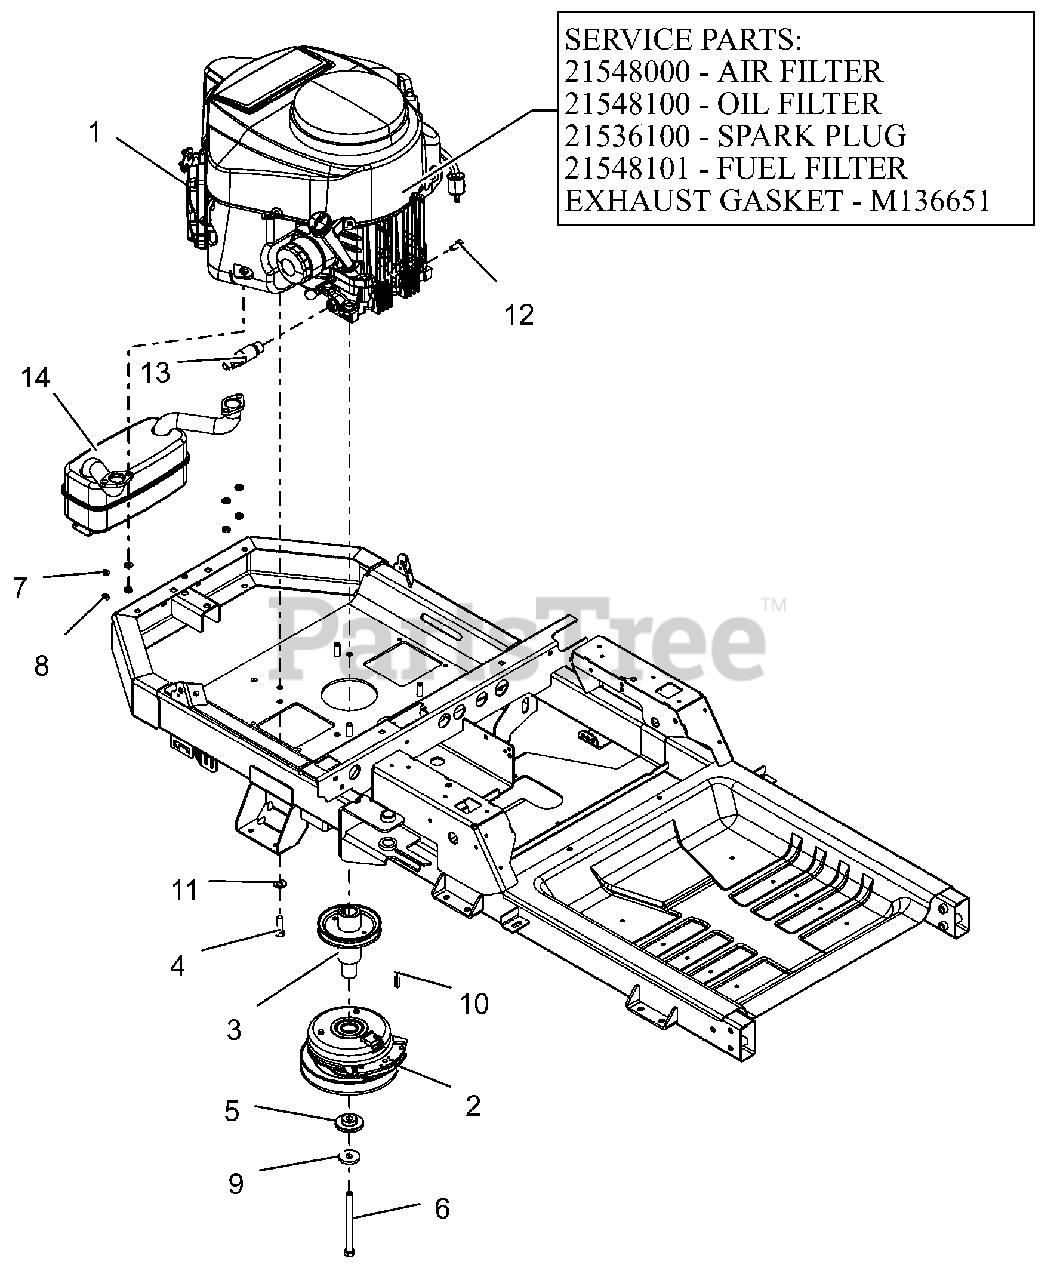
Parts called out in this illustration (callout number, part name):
1	ENGINE, KAWASAKI FR651V 21.5HP
1	AIR FILTER, KAWASAKI FR
1	OIL FILTER, KAWASAKI FR
1	PLUG, SPARK
1	FUEL FILTER-KAWASAKI FR
1	GASKET, MUFFLER #
2	CLUTCH,105FTLB MONOPOLE 6.83"
3	WLDMT, DRIVE SHEAVE (LG XL)CZC
4	BLT, HEX .38-16X1.25 G5 ZCC NT
5	BSHG-FLG .469X1.06X.574X2.0
6	BLT-HEX.438-20X5 GR8 YZ NYTORQ
7	WSHR,LK-REG .312X.078 ZCC
8	NUT,NYL M8-1.25 G8.8 ZCC
9	WASHER, 7/16" SPRING DISK
10	KEY-SQ .25 X 1.25 X .25 SAE
11	WASHER, 3/8" SPRING DISC
12	BLT, HEX M8-1.25X20 G8.8 ZCC
13	DRAIN, OIL M20X2.5
14	MUFFLER - KAWASAKI
